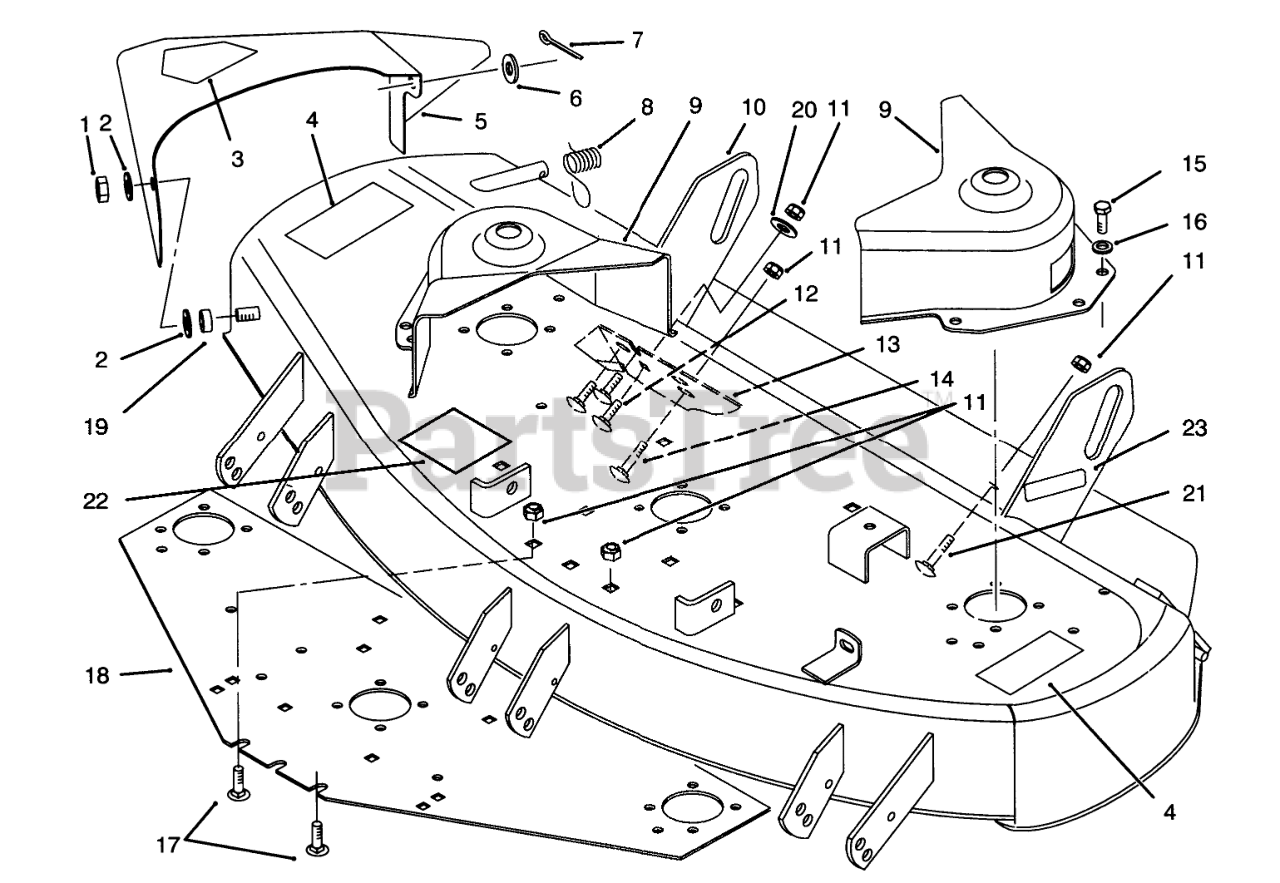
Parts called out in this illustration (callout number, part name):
1	NUT-HJ
2	WASHER
3	DECAL-DANGER
4	DECAL-DANGER
5	Chute Assembly (Incl. Ref. #3)
6	WASHER-FLAT
7	PIN-COTTER
8	SPRING-DEFLECTOR
9	COVER-BELT
10	Deck Assembly (Incl. Ref. #4, 22 &23
11	NUT-LOCK, NI
12	SCREW-CARR
13	PLATE-WEAR RH
14	SCREW-CARR
15	SCREW-HWH
16	WASHER-FLAT
17	SCREW-CARR
18	PLATE-DECK
19	BUSHING-PIVOT
20	WASHER-FLAT
21	SCREW-CARR
22	DECAL-BELT INSTALL
23	Decal-Attach-A-Matic
